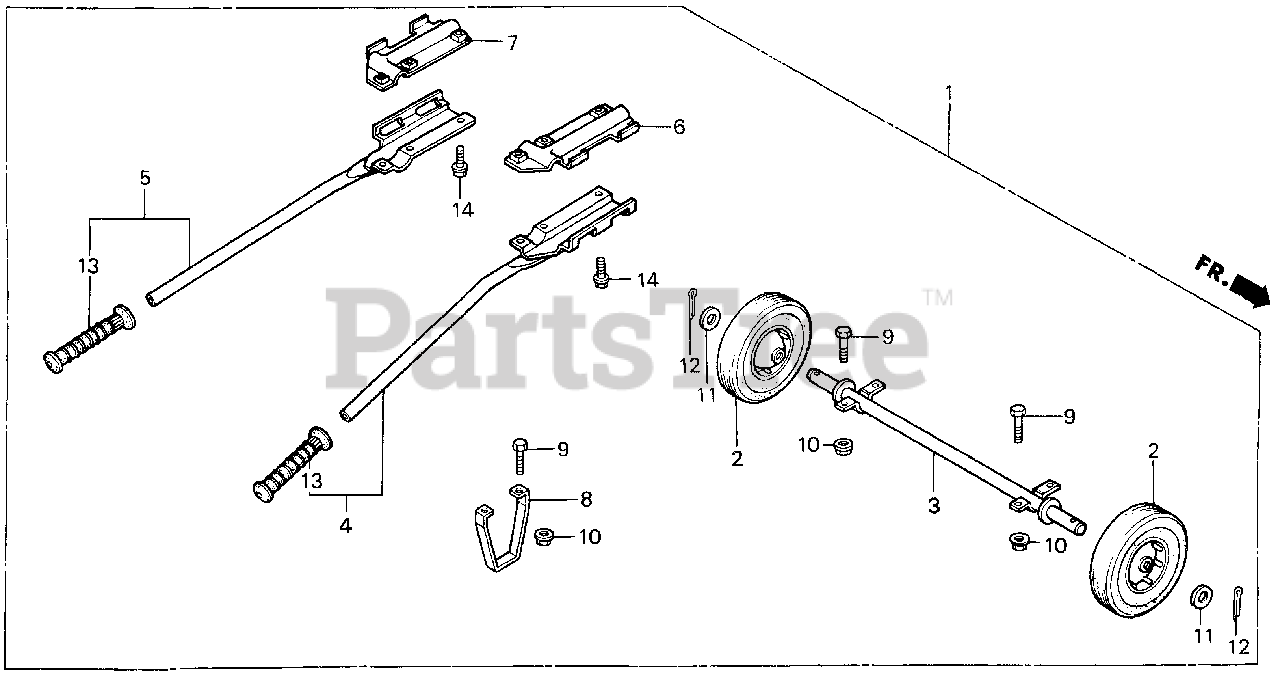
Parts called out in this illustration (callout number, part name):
1	WHEEL KIT (2-WHEELS)
2	WHEEL (10"X2.75")
3	SHAFT, WHEEL
4	HANDLE, R. (LOWER)
5	HANDLE, L. (LOWER)
6	BRACKET, R. HANDLE (UPPER)
7	BRACKET, L. HANDLE (UPPER)
9	BOLT, HEX. (8X16)
10	NUT, FLANGE (8MM)
11	WASHER, FLAT (20MM)
12	PIN, COTTER (4.0X30)
13	GRIP, R. HANDLEBAR
14	BOLT, FLANGE (8X16)
